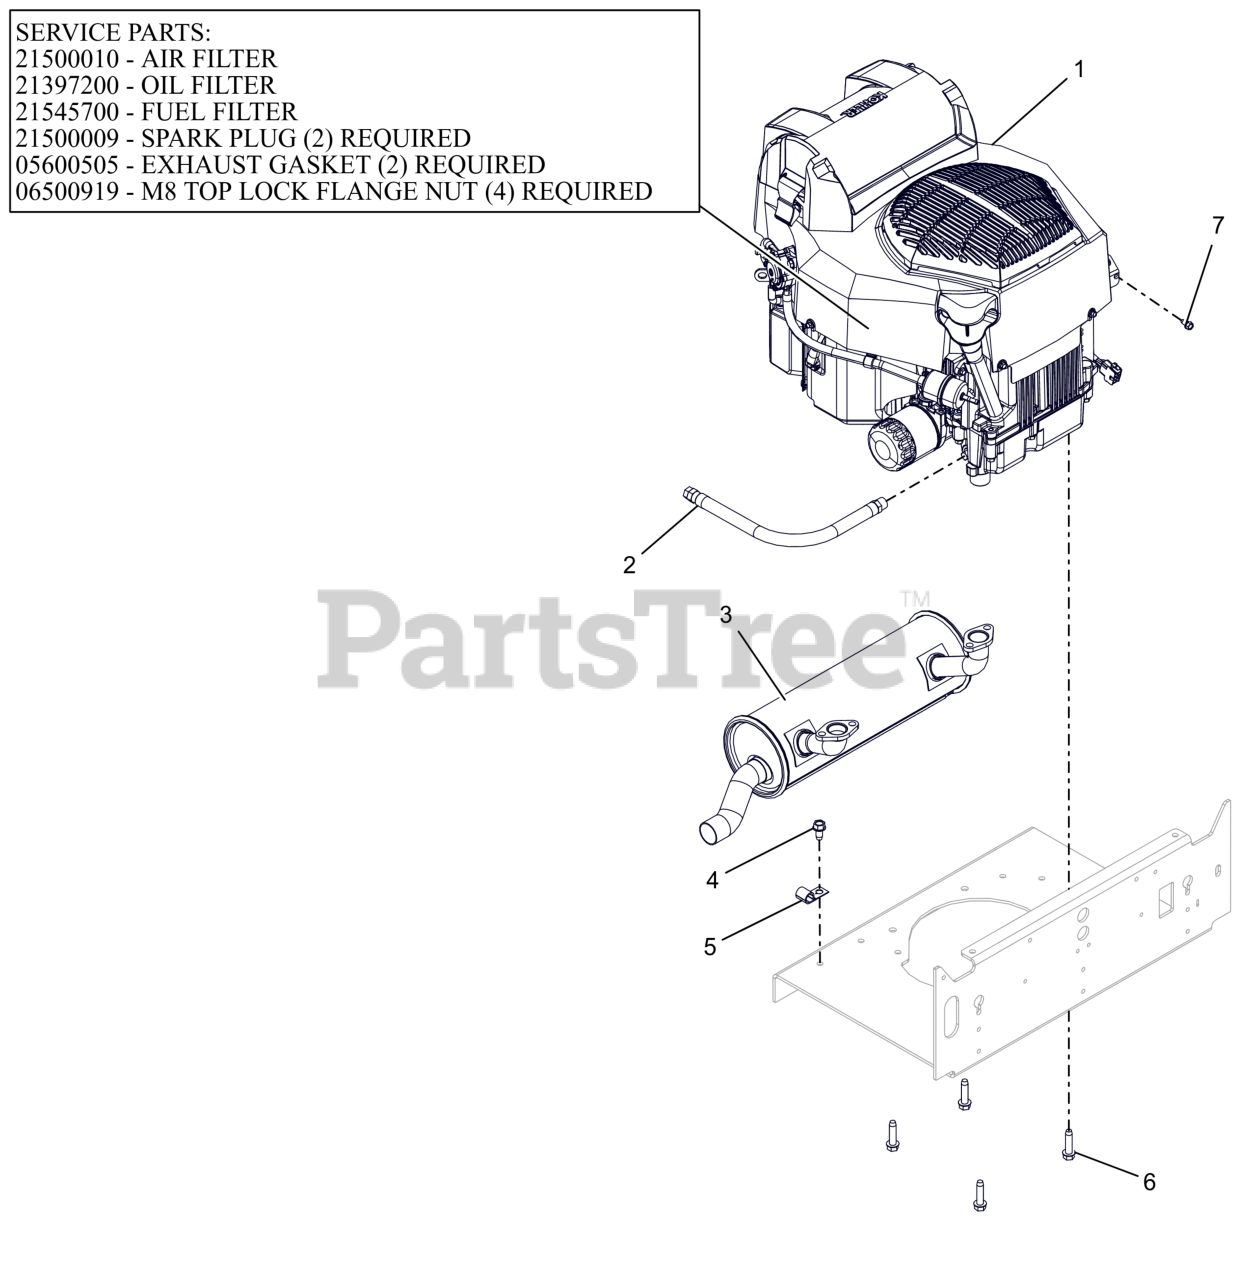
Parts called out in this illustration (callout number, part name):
1	ENGINE, KOHLER ZT730 CONFIDANT
1	AIR CLEANER, KOHLER CONFIDANT
1	FILTER, OIL - KOH CV20
1	FILTER-FUEL KOHLER COURAGE PRO
1	PLUG, SPARK KOHLER
1	GASKET, MUFFLER KOHLER TWIN
1	NUT-LK-TOP-FLG M8 ZCC
2	HOSE, OIL DRAIN
3	MUFFLER, ZT730/ZT740
4	SCR,TAP .375-16X.75 HWH TR ZCC
6	SCR-TAP .38-16X1.50 HWH ZCC
7	SCR-TAP .25-20X.50 HWH ZCC
